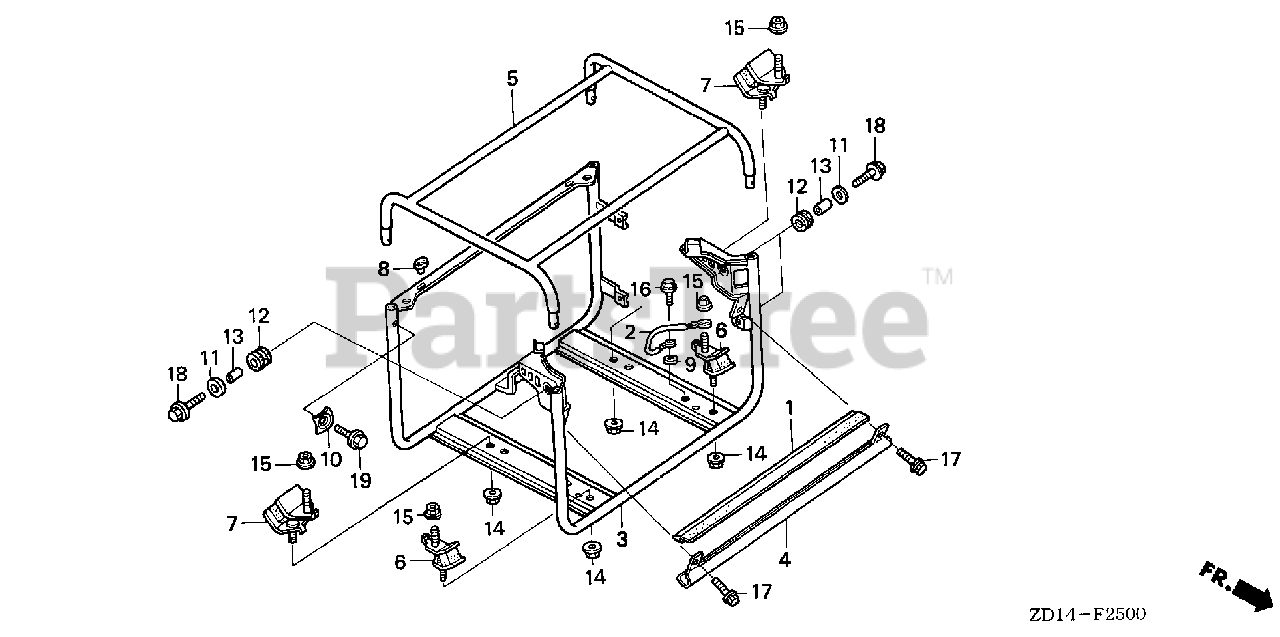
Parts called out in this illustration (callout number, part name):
2	CABLE, GROUND
3	FRAME (LOWER) *NH105* (MAT BLACK)
4	CHANNEL, FR. *NH105* (MAT BLACK)
5	FRAME (UPPER) *NH105* (MAT BLACK)
6	RUBBER (LOWER)
7	RUBBER (LOWER)
8	STOPPER, DISCHARGE GUARD
9	WASHER, LOCK (6MM)
10	WASHER, FRAME JOINT
11	WASHER, FLAT (20MM)
12	RUBBER, CONTROL BOX
13	COLLAR, CONTROL BOX
14	NUT, FLANGE (8MM)
15	NUT, FLANGE (10MM)
16	BOLT, FLANGE (6X10)
17	BOLT, FLANGE (6X12)
18	BOLT, FLANGE (6X18)
19	BOLT, FLANGE (8X16)
